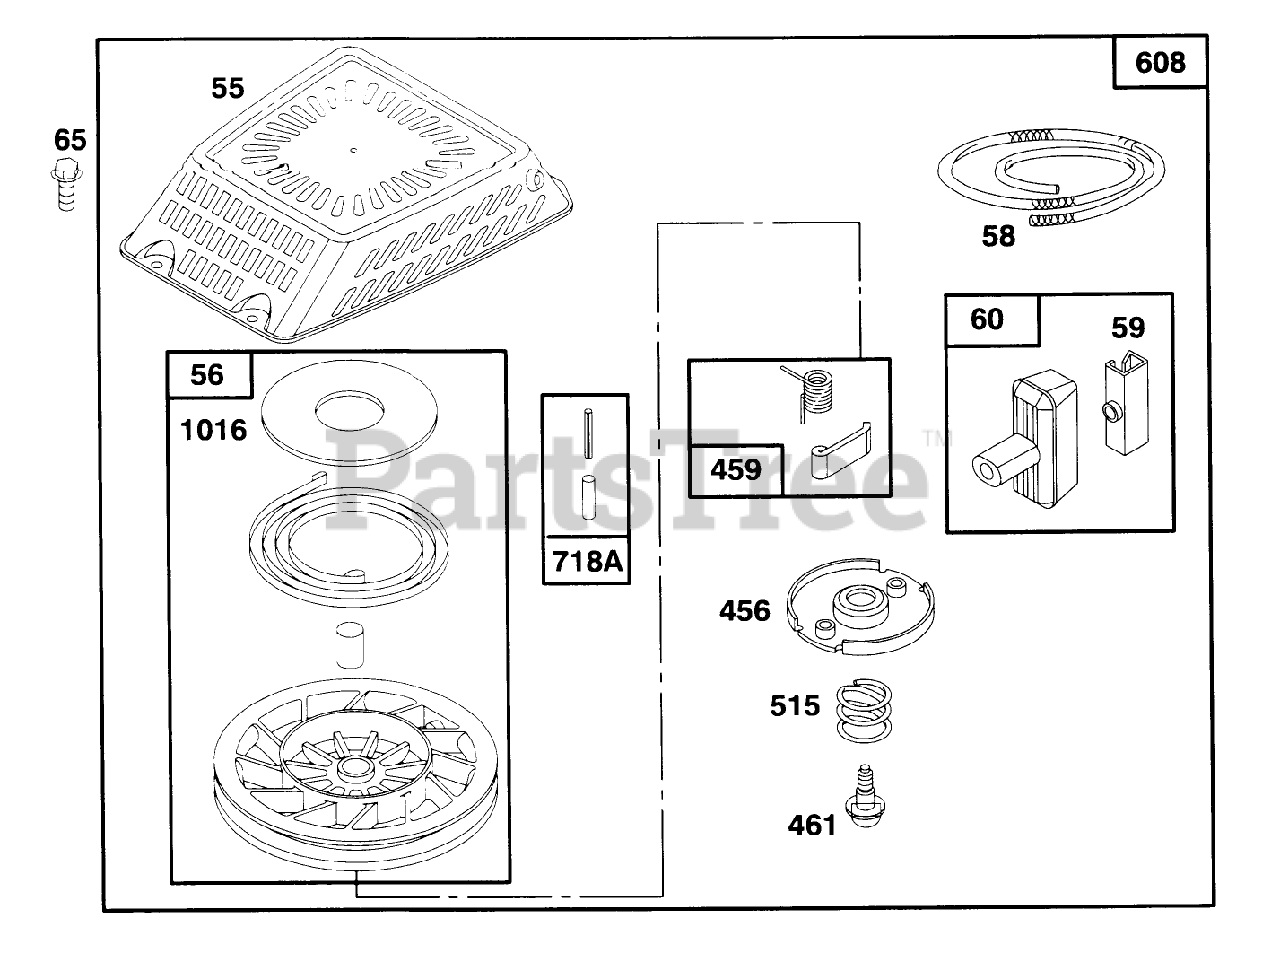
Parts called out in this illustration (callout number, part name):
60	HANDLE-REWIND STARTER
456	RETAINER - SPRING
515	SPRING - RETAINER
